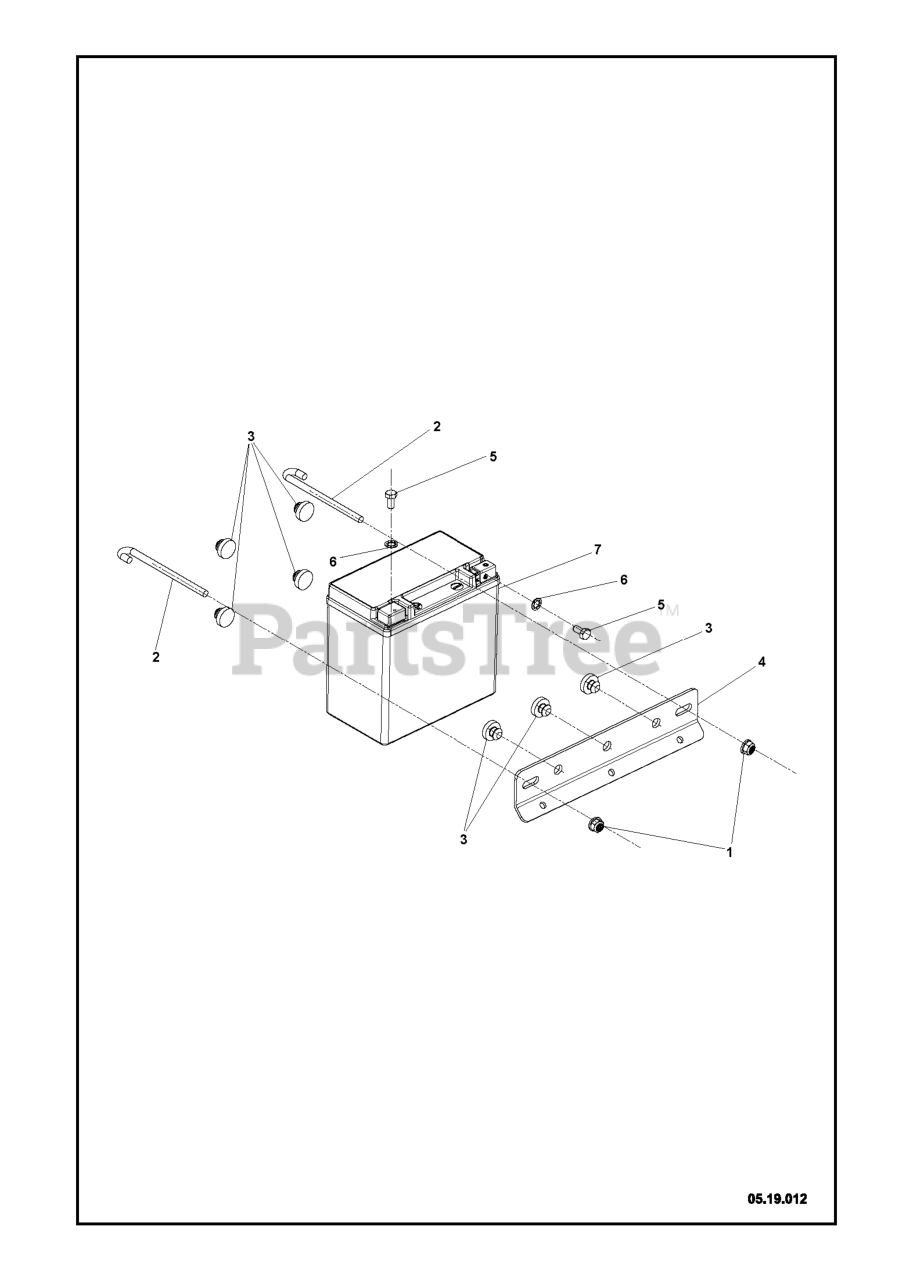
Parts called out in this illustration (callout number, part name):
1	NUT FLG, NYLOCK, 1/4-20 GR G C
2	HOOK.J.BATTERY
3	GROMMET.BUMPER
5	Bolts
6	WASHER 1/4 INT TOOTH
7	Batteries
